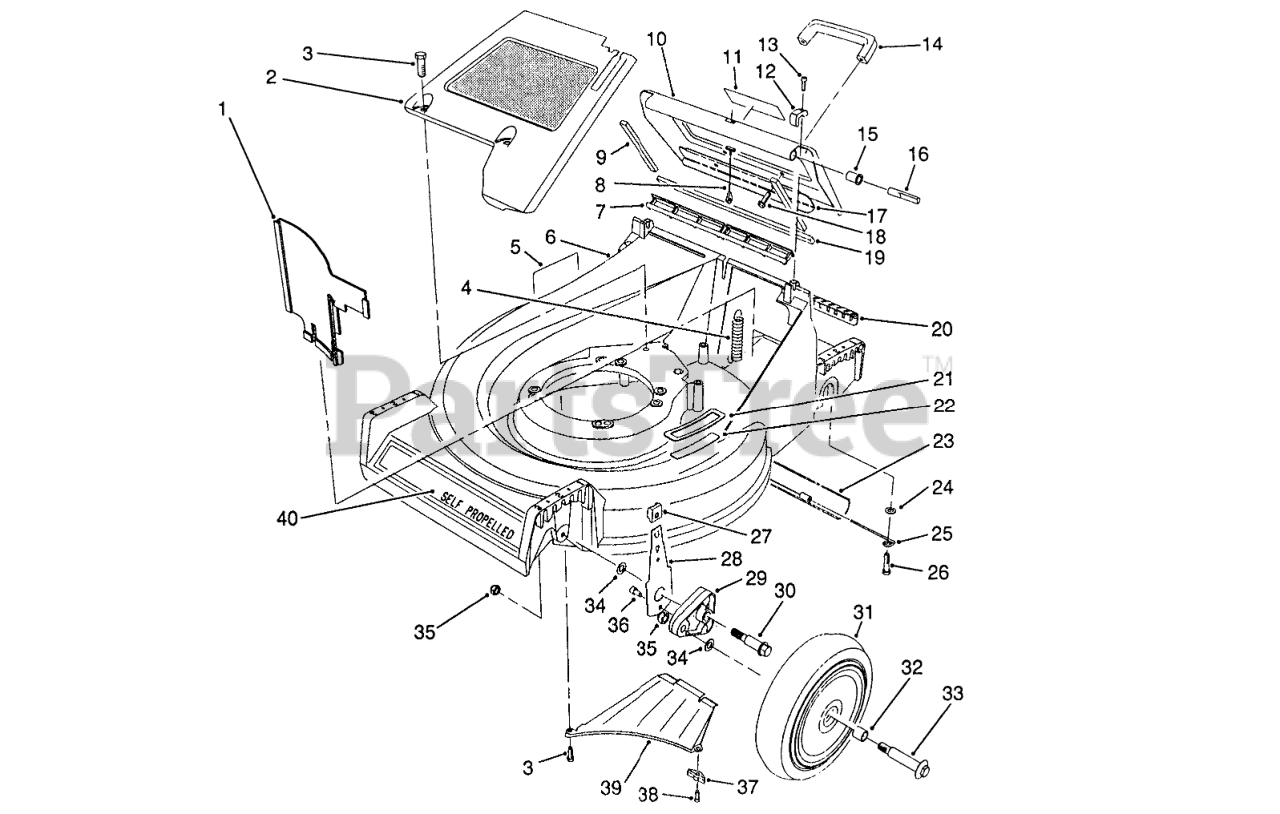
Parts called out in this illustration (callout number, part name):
1	PANEL-VERTICAL
2	PaneI-Screen
3	SCREW-HWHTF
4	EXTENSION-SPRING
5	DECAL-DANGER
6	Housing-21" (Incl. Ref. #5 & 22)
7	DOOR SEAL
8	DOOR CABLE
9	DOOR SIDE SEAL
10	Door-Discharge (Incl. Ref. #9, 11, 17 & 19)
11	DECAL - WARNING
12	HINGE CLAMP
13	SCREW-HSH
14	HANDLE-DOOR
15	DOOR BUSHING
16	HINGE PIN
17	DOOR - BRACE
18	SCREW-HWH
19	DOOR END SEAL
20	ACCESS COVER
21	STEP PAD
22	STEP PAD DECAL
23	TRAILING SHIELD
24	WASHER-PLAIN
25	SHIELD HANGER
26	SCREW-SHOULDER
27	KNOB-ARM
28	FRONT SPRING ARM ASM
29	ARM-PIVOT, FRONT
30	BOLT-SHOULDER
31	Wheel & Tire Assembly (Incl. Ref. #32)
32	BUSHING
33	WHEEL BOLT
34	WASHER
35	NUT-LOCK
36	SCREW-HSH, THREAD FORMING
37	Bracket-Discharge
38	SCREW-HWHTF
39	Ramp Discharge
40	DECAL - DECK
